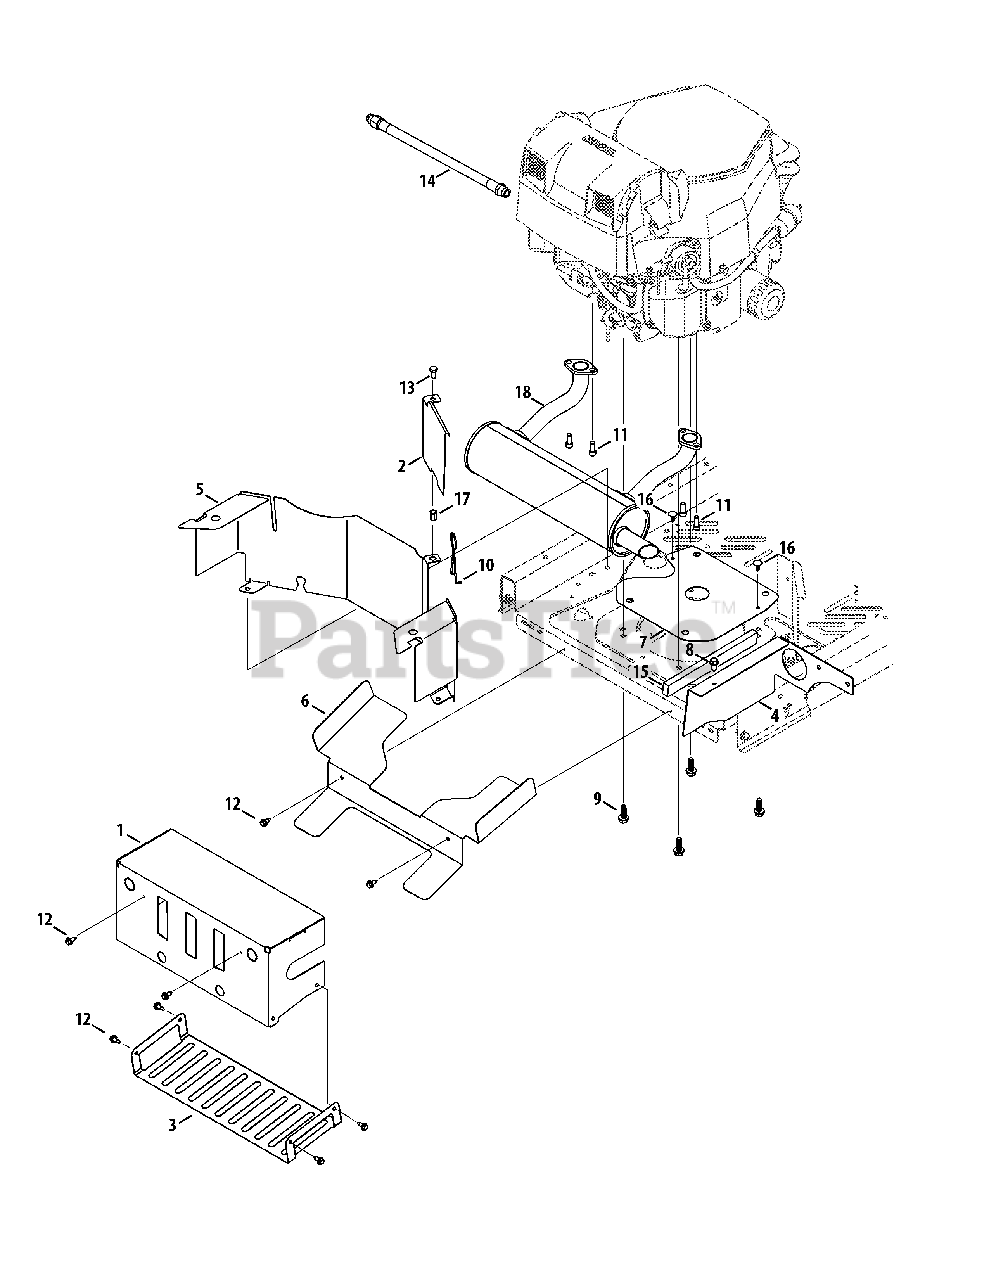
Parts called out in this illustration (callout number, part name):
1	Muffler Shield Bracket
2	Engine Shield Bracket
3	Lower Muffler Shield Bracket
4	Pod Shield Bracket, RH
5	Engine Shield Bracket
6	Muffler Mounting Bracket
7	Engine Shield Plate
8	Hex Washer Screw, 5/16-18 x .750
9	Screw, 3/8-16 x 1.00
10	Tank Support Rod
11	Socket Head Screw, 5/16-18 x .750
12	Hex Washer Screw, 1/4-20 x .625
13	Hex Cap Screw, 5/16-18 x .625
14	Oil Drain Hose
15	Foam Tape, 1.00 x .500 x 9.375
16	Ratchet Clip, .250
17	Nut, 5/16-18
18	Twin Muffler
